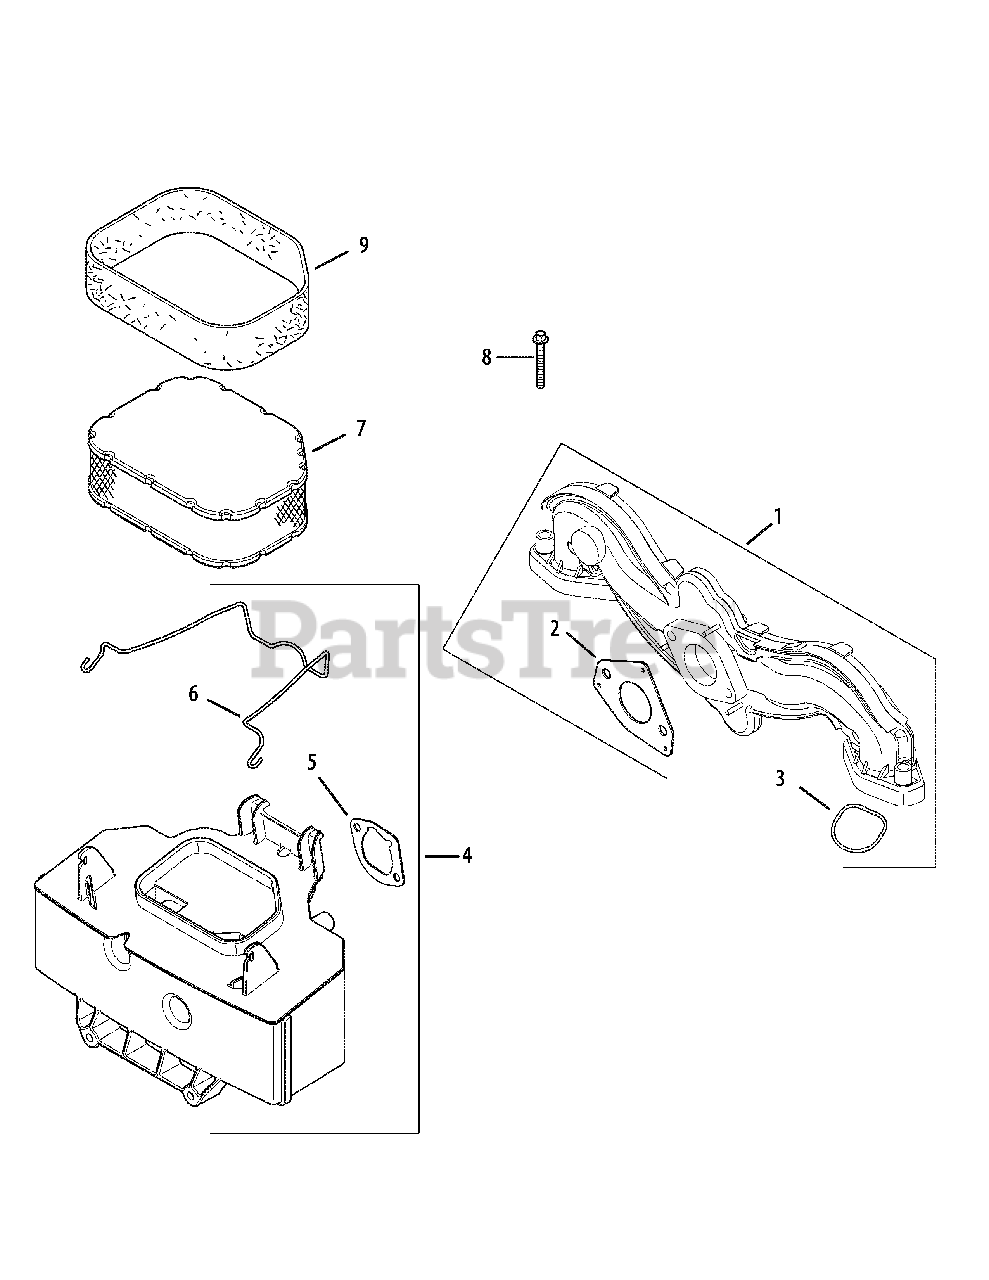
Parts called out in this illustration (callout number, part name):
1	Manifold, intake
2	Gasket, carburetor
3	O-Ring, intake port
4	Base, air cleaner
5	Gasket, air cleaner base
6	Latch, air cleaner element
7	Element, air cleaner
8	Screw, hex.flange M6x1.0x40
9	Pre-cleaner, element
